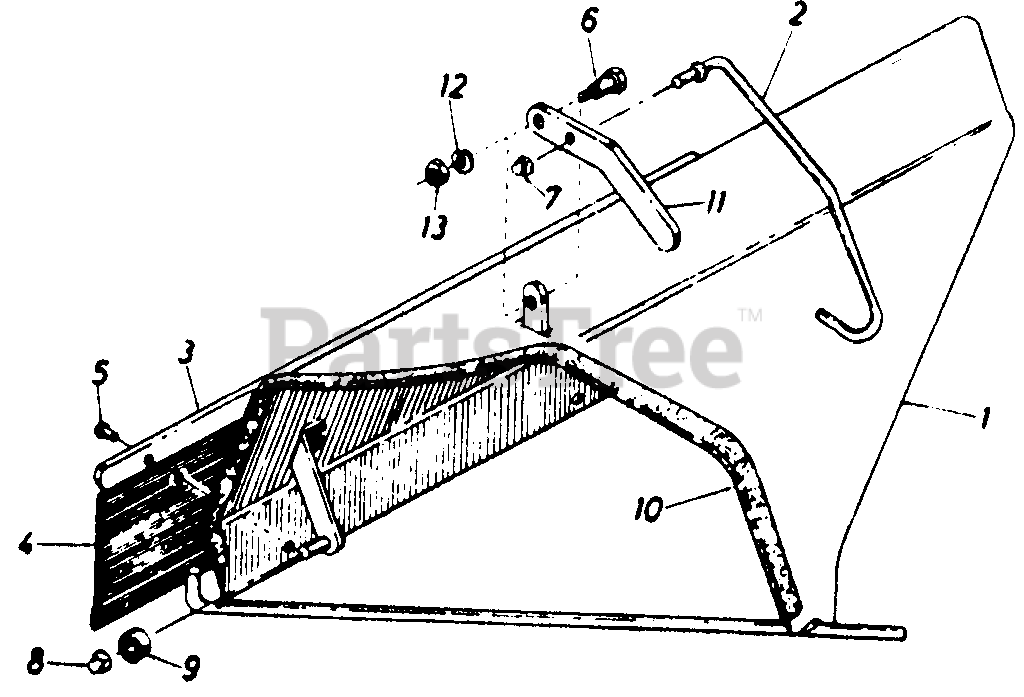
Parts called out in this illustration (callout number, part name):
1	Deflector Ass'y.
2	Hook Ass'y.
3	Retaining Strip
5	Rivet
6	Shld. Bolt.375" Dia. x.171 Lg.
7	Palnut 1/4" Rod
8	Palnut 3/8" Rod
9	Roller
10	Moulding
11	Latch Arm
12	L Wash. 1/4" I. D.
13	Hex Nut 1/4-20 Thd.*
